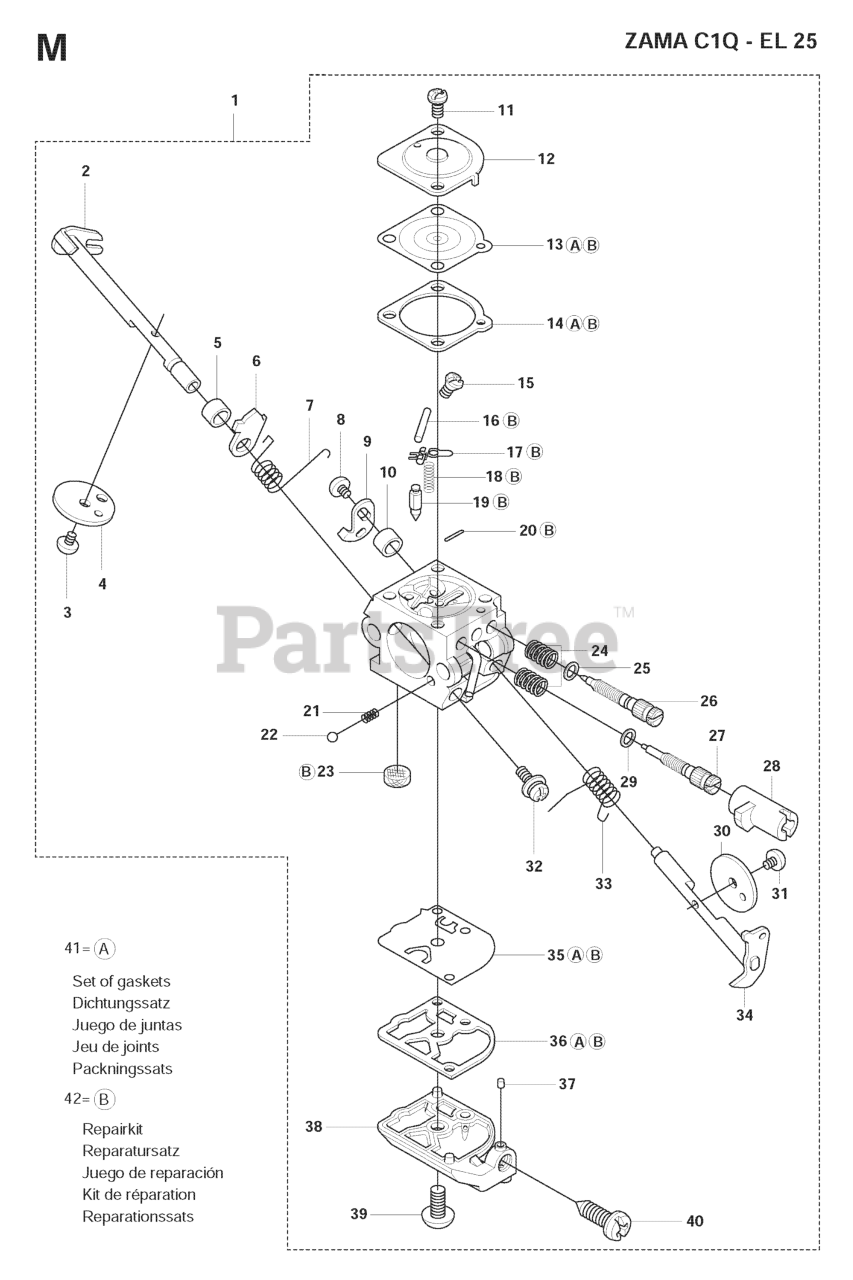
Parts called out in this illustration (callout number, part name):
1	CARBURETOR
2	CHOKE SHAFT
4	DISC
10	LEVER
16	PIN RETAINING SCREW
18	SPRING
19	INLET NEEDLE
24	SPRING
26	LOW SPEED NEEDLE
27	NEEDLE HIGH SPEED
30	THROTTLE FLAP
33	SPRING THROTTLE
35	PUMP DIAPHRAGM
41	GASKET KIT (ZAMA GND39)
42	CARBURETOR KIT (ZAMA RB69)
